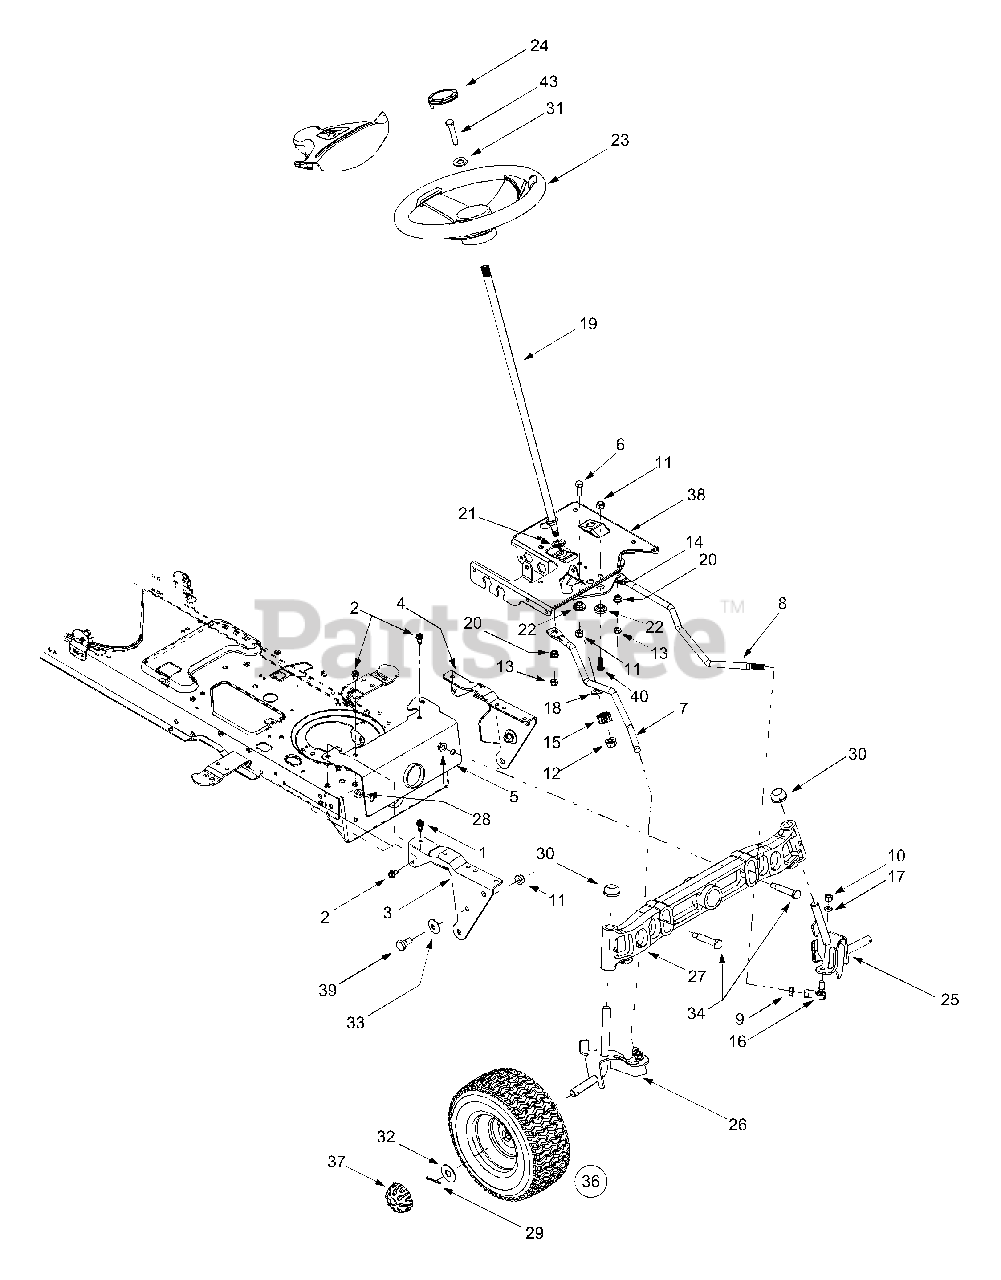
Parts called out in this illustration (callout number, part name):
1	Self-tapping Screw, 5/16-18 x .75
2	Self-tapping Screw, 16-18 x .625
6	Hex Cap Screw, 3/8-16 x 1.0 (Grade 5)
7	RH Drag Link
8	LH Drag Link
9	Jam Nut, 7/16-20 (Grade 2)
10	Hex Nut, 3/8-24 (Grade 2)
11	Lock Nut, 3/8-16
12	Flange Lock Nut, 7/16-20
13	Lock Nut, 5/16-18
14	Steering Segment, 11/90 Ratio
15	Steering Pinion Gear
16	Ball Joint, 7/16-20
17	Lock Washer, 3/8
18	Flat Washer, .51 x 1.12 x .06
19	Steering Shaft, .625 OD x 24.4
20	Plastic Bushing, .38 ID
21	Hex Flange Bearing, 5/8
22	Shoulder Spacer, .38 ID
23	Steering Wheel: 3 Spoke
23	Steering Wheel: 3 Spoke Soft Grip
24	Steering Wheel Cap, Small (Shown)
24	Steering Wheel Cap, Large
25	LH Axle Assembly, .75 Diameter (Models with 46-inch Deck)
25	LH Axle Assembly, .75 Diameter (Models with 42-inch Deck)
26	RH Axle Assembly, .75 Diameter (Models with 46-inch Deck)
26	RH Axle Assembly, .75 Diameter (Models with 42-inch Deck)
27	Cast Iron Pivot Bar w/ Fittings, .75
28	Lock Nut, 3/8-16
29	Cotter Pin
30	Push Cap, .750
31	Bell Washer, .34 x .872
32	Flat Washer, .78 x 1.59 x .06
33	Bell Washer, .39 x 1.13 x .062
34	Shoulder Screw, .5 x 2.2, 3/8-16
35	Hex Bolt, 5/16-18 X 1
37	Hub Cap
38	Steering Support Bracket
39	Shoulder Screw, 3/8-16
40	Hex Screw 3/8-16 x 1.0
